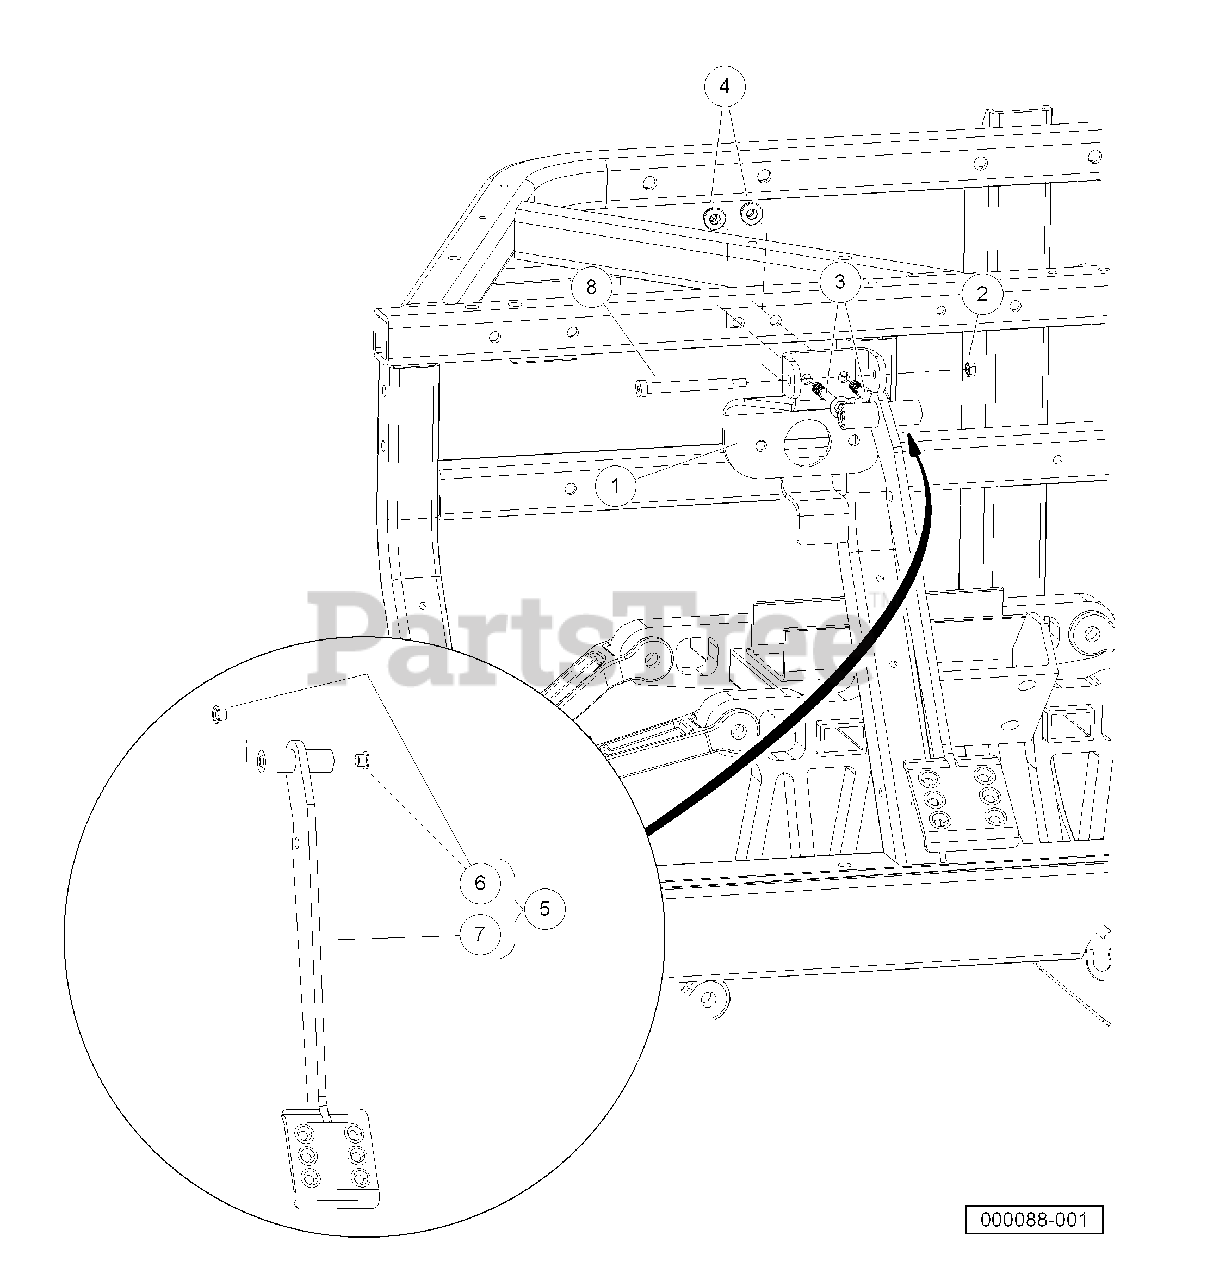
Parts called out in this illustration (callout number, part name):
1	Bracket, Pedal, Brake
2	Nut M6x1 Mech Def Center
3	Bolt Flanged Head, M8 X 1.25 X 65
4	Lock Nut, Flg M8 X 1.25 Nylon
5	Asm, Pedal, Brake, Hung
6	Bushing, Greaseless
7	Weldment, Pedal, Brake, Hung
8	Bolt, Shoulder, M8 X 70, Hc
